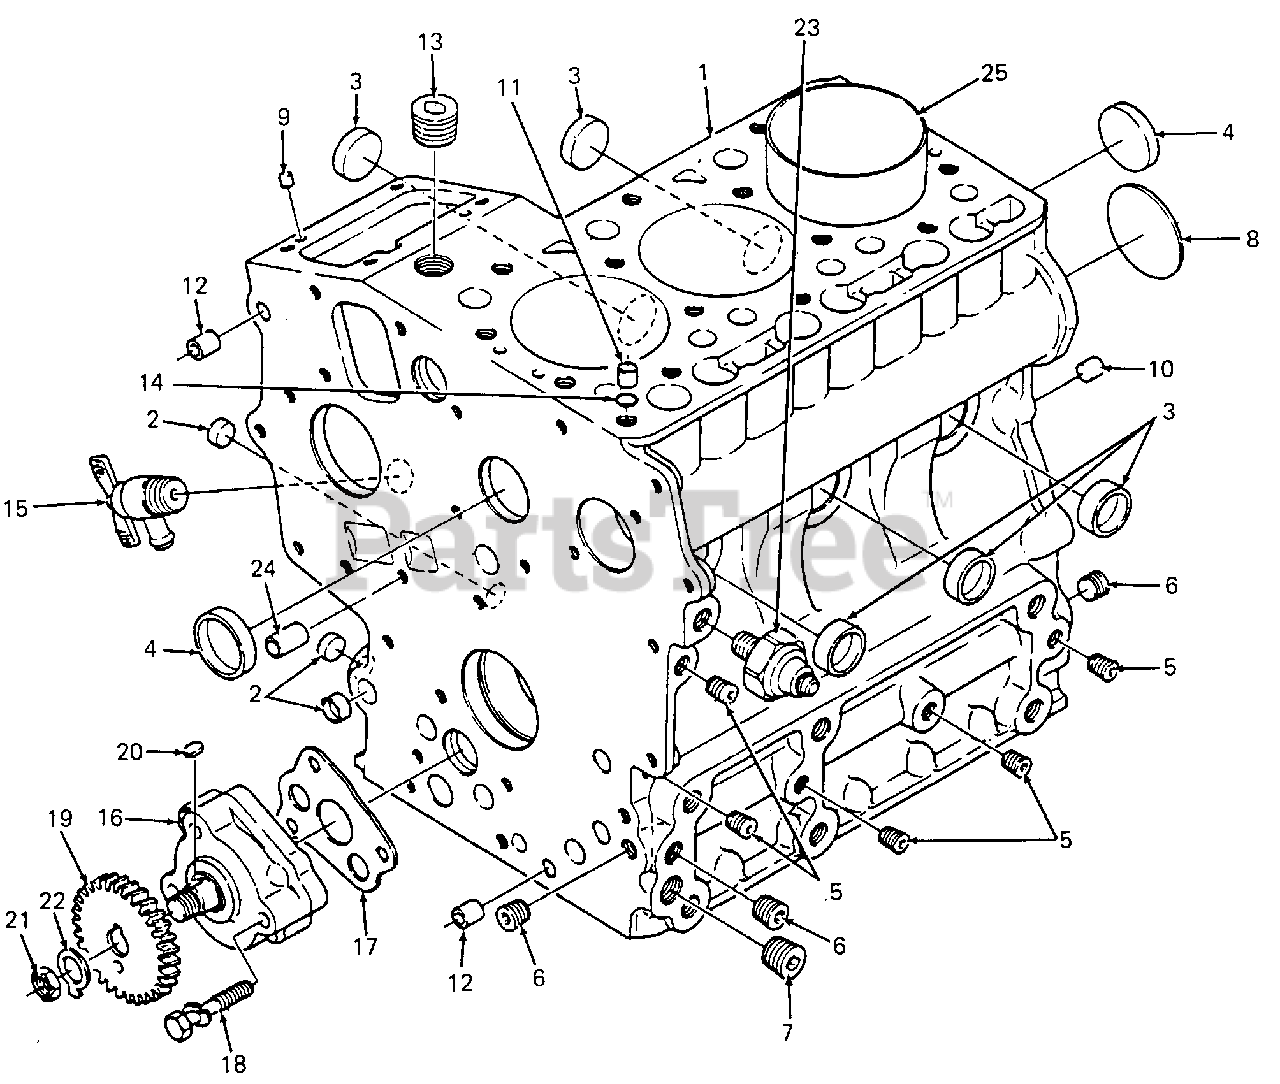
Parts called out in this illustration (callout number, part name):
1	Crankcase Assy
9	Pin, Straight
10	Pin, Straight
15	Handle, Drain Cock
17	Gasket, Oil Pump
18	Screw, Hex Cap w/Washer
19	Gear, Oil Pump Drive
23	Switch, Oil
25	Lining, Cylinder
